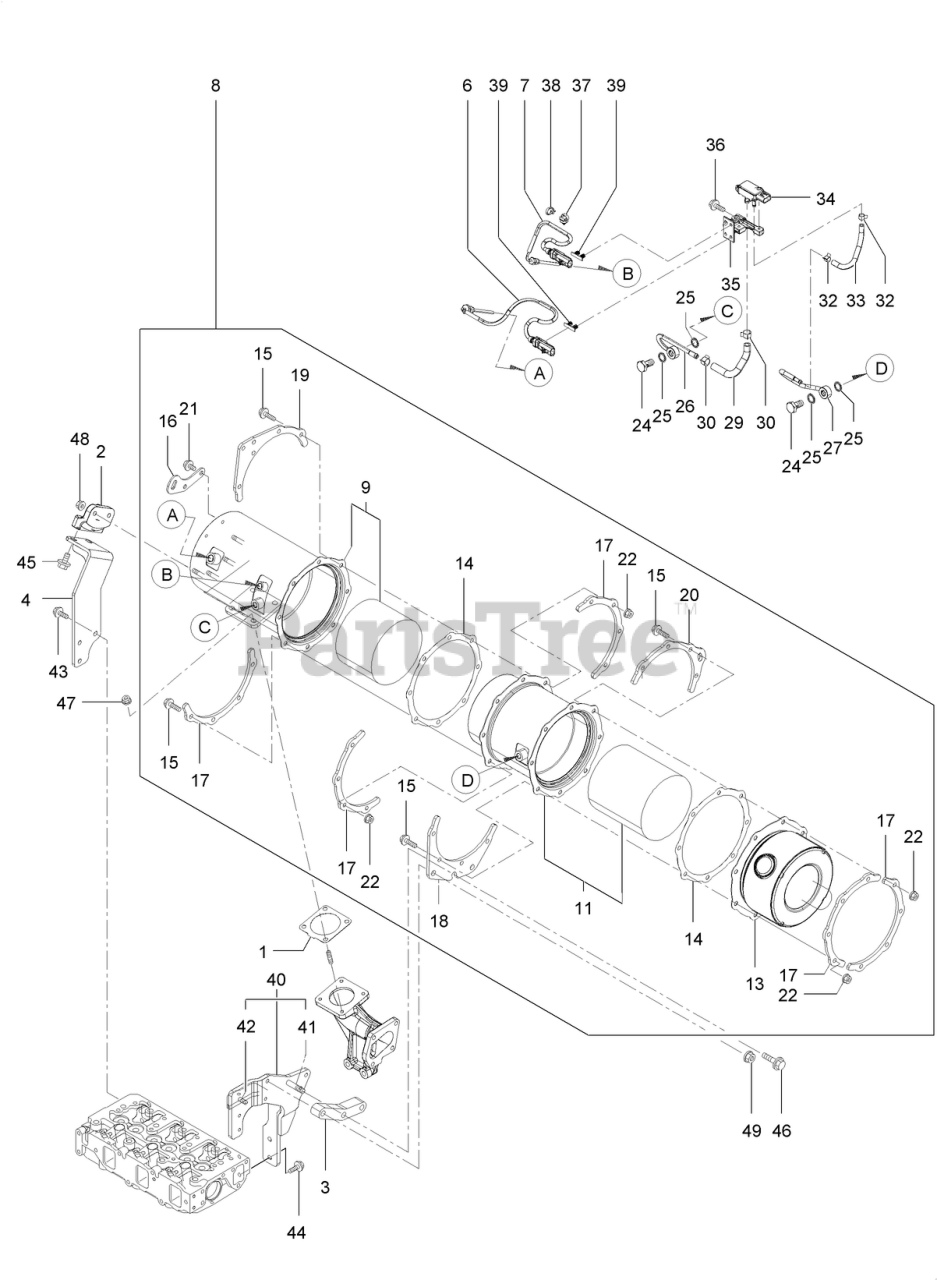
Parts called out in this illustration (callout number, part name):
2	STAY-D P F
3	STAY, DPF
4	STAY, DPF
6	SENSOR-TEMP, EXHAUST
7	SENSOR-TEMP, EXHAUST
8	D P F ASM
9	CASE, DOC
11	CASE, SOOT FILTER
13	SILENCER-D P F
14	GASKET-D P F
16	LIFTER-D P F
17	STIFFENER-D P F, A
18	STIFFENER, DPF B
19	STIFFENER, DPF C
20	STIFFENER-D P F, C
24	BOLT-JOINT, PIPE
25	GASKET-SENSOR
26	SENSOR PIPE ASM
27	SENSOR PIPE ASM
29	HOSE-PRESSURE
30	Clip-Hose
32	Clip-Hose
33	HOSE, EXHAUST PRESSURE
34	SENSOR-PRESSURE
35	BRACKET-SENSOR
37	BAND-CLIP
39	CLIP-CONNNECTOR
40	STAY, DPF
41	BOLT-STUD
42	BOLT-STUD
46	BOLT, M10X 40 PLATED
